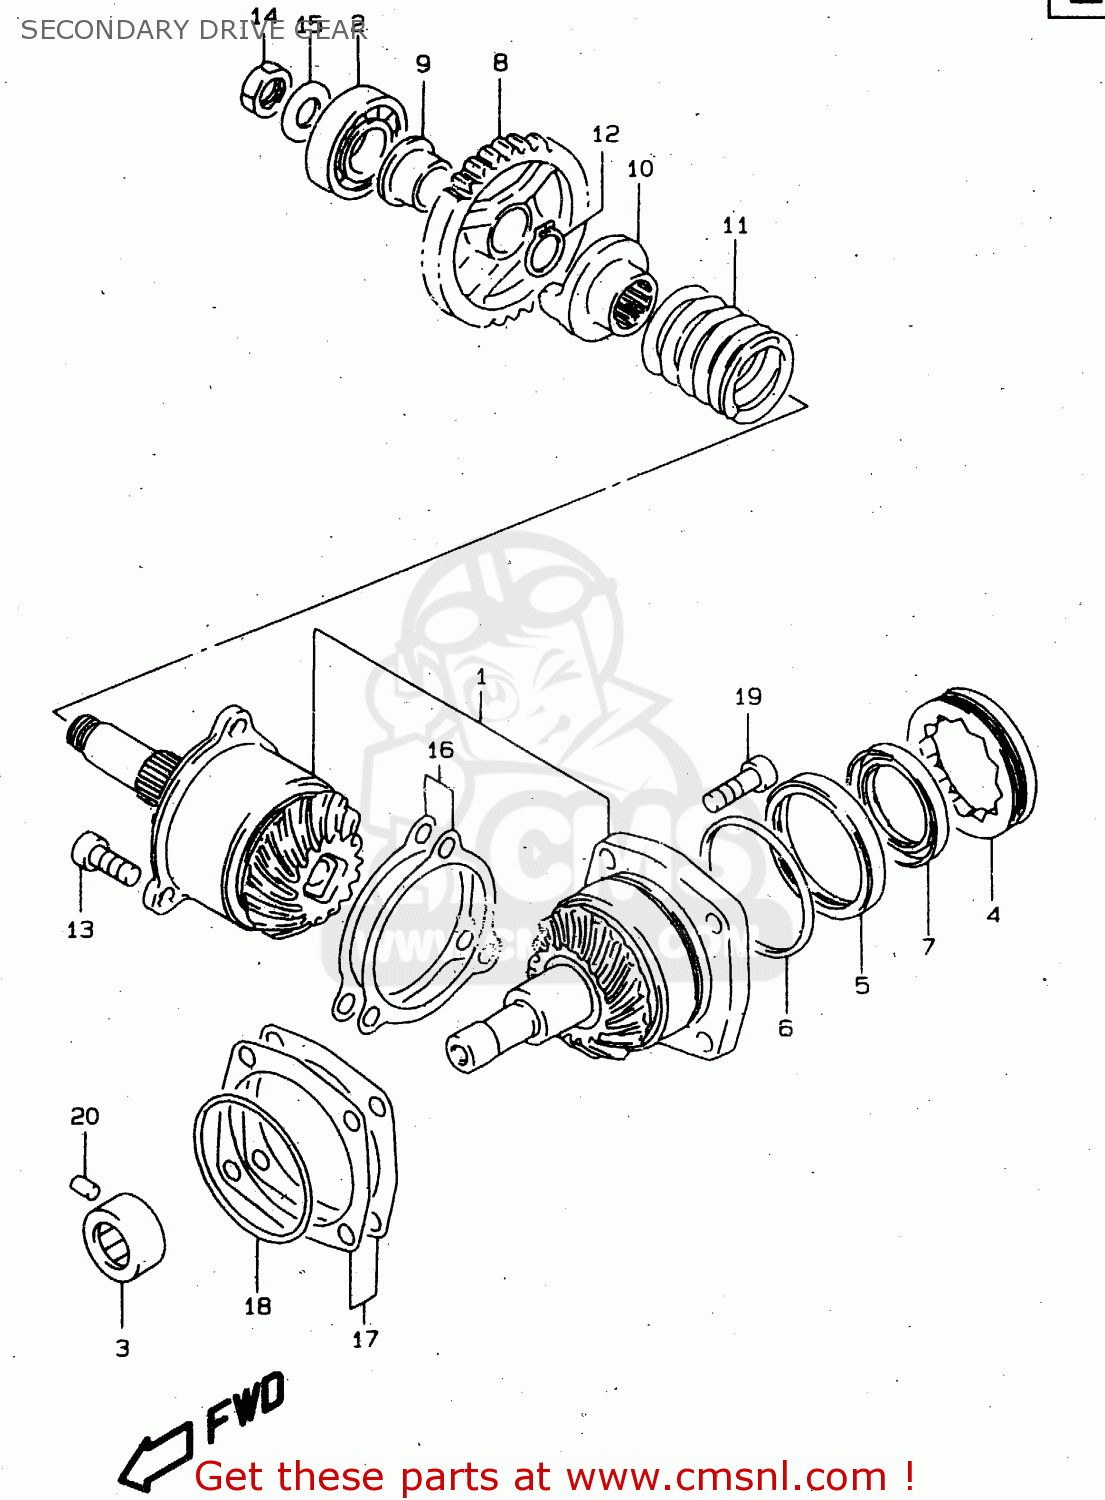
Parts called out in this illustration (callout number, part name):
1	GEAR & HOUSING SET,SECONDARY
2	BEARING(20X52X15)
3	BEARING(20X34X16)
4	STOPPER,SEC DRIVEN BEARING
5	HOUSING,OIL SEAL
6	O RING(D:1.2,ID:59.6)
7	SEAL,OIL(38X54X8.5)
8	GEAR,REDUCTION DRIVEN(NT:30)
9	BUSH,REDUCTION DRIVEN GEAR
10	DOG,OUTPUT CAM
11	SPRING
12	CIRCLIP
13	BOLT
14	NUT
15	WASHER(16X29X4)
16	SHIM SET,SEC DRIVE GEAR
17	SHIM SET,SEC DRIVEN HOUSING
18	O RING(D:2.1,ID:66.2)
19	BOLT
20	PIN
